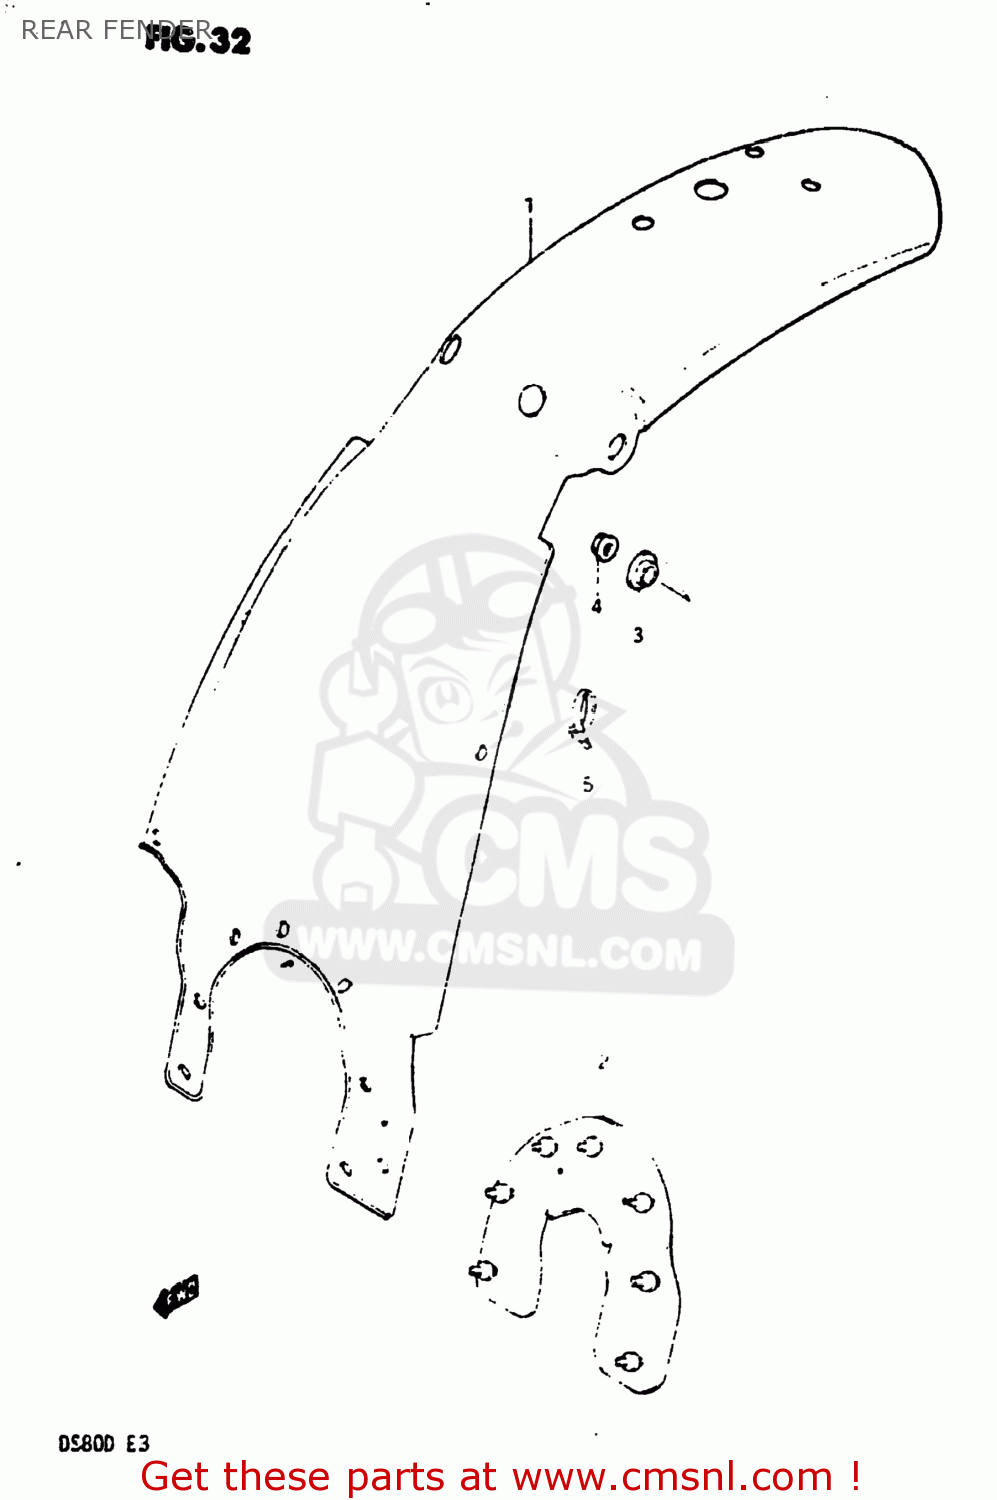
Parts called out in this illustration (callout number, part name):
1	FENDER,REAR
2	MUDGUARD,RR FENDER
3	WASHER
4	NUT
5	CLAMP
